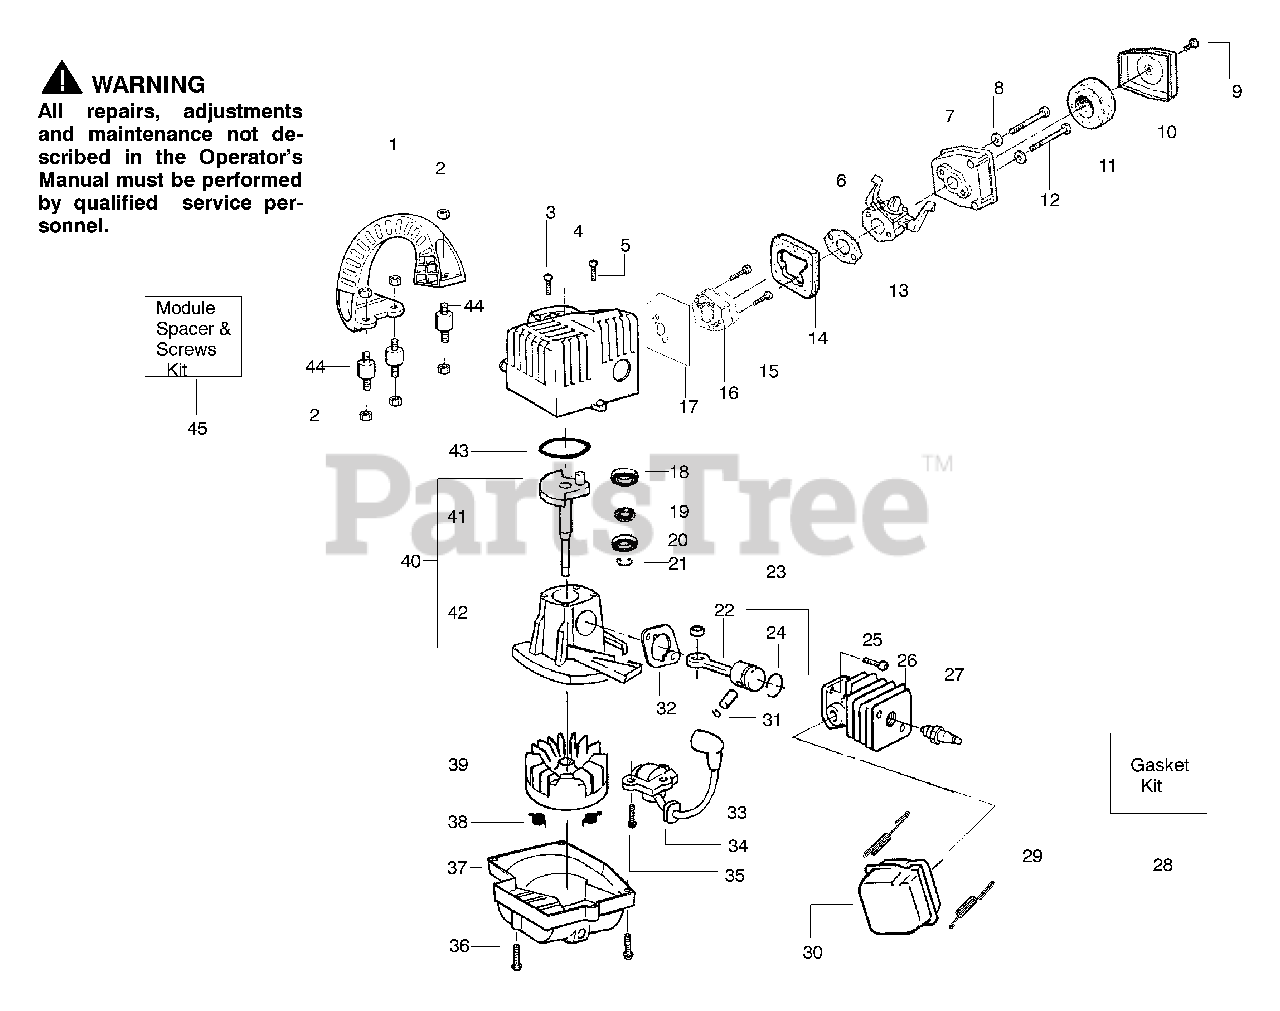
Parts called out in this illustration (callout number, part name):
3	Screw
6	Gasket-Carb.(kit)
10	Cover-Air Box
11	Foam-Air Filter
12	Screw (Type 4)
12	Screw (Type 5)
13	Carburetor Ass'y. Kit
14	Foam-Air Dam
16	Carb. Adaptor (Type 4)
16	Carb. Adaptor (Type 5)
17	Gasket-Carb. Adap.(kit)
18	Inner Bearing
19	Kit-Crankcase Seal
20	Outer Bearing
21	Retainer Ring (C'shaft)
22	Connecting Rod Ass'y.
23	Kit-Piston
24	Piston Ring
26	Cylinder
27	Spark Plug (RCJ-6Y)
28	Kit-Gasket
29	Muffler Spring
30	Kit-Muffler Ass'y.
31	Wrist Pin Retainer
32	Gasket-Cylinder(kit)
33	Ignition Module
34	Grommet-Ign. Module
36	Screw
37	Fan Housing
38	Spring-Starter Dog
39	Flywheel Ass'y.
40	C'case & C'shaft Ass'y.
41	Crankshaft Ass'y.
42	Crankcase Ass'y.
43	O-Ring C'case (kit)
44	Isolator
45	Kit-Module Spacer & Screws
